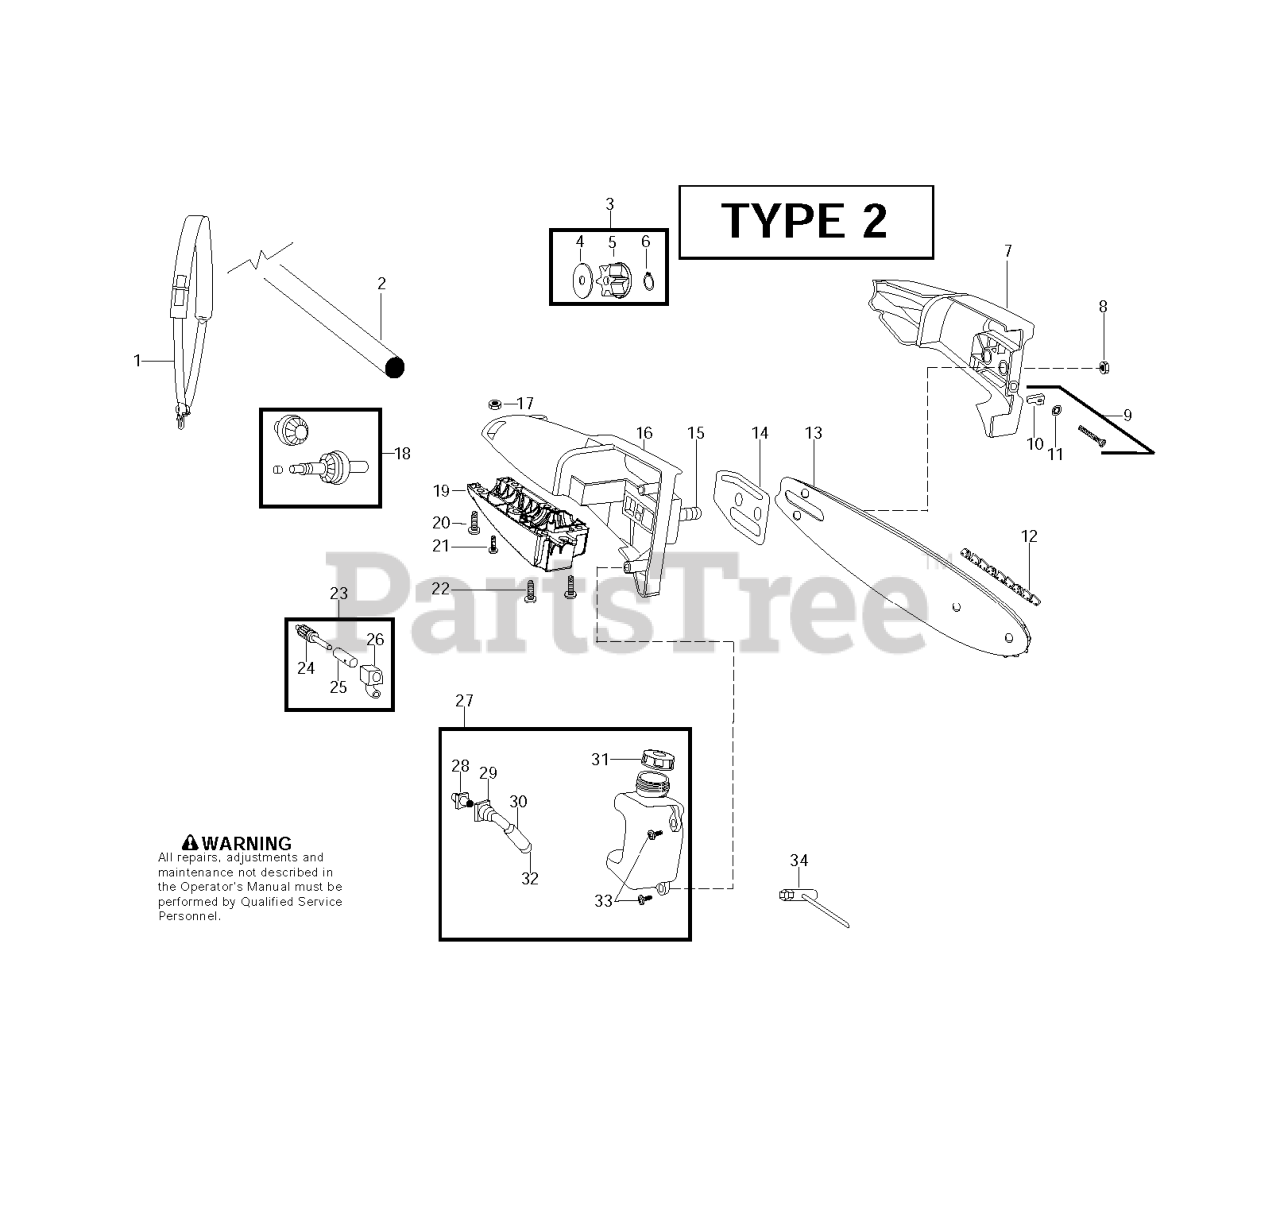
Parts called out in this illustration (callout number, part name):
1	Harness-w/o warning
2	KIT ASSY DRIVESHAFT PRUNER LDX
6	RING SPROCKET RETAINER
7	BAR CLAMP ASSY
9	KIT.RETAINER.BAR ADJUSTMENT
10	ADJUST PIN,BAR 36/41
12	Chain - 8"
14	PAD BAR PLATE
16	GEAR HOUSING UPPER
18	KIT GEAR ASSY
19	GEAR HOUSING LOWER
20	SCR 10-24 MS LDK PAN PH
21	SCREW-10-14 X 1/2 PLASTITE
22	SCREW-10-14 X 13/16 (PL
24	ASSY GEAR PLUNGER
27	ASSY OIL TANK PRUNER ATTACH
28	OIL PUMP FITTING
29	LINE OIL INTAKE
30	FILTER
31	CAP OIL
32	PLUG
34	WRENCH-BAR
